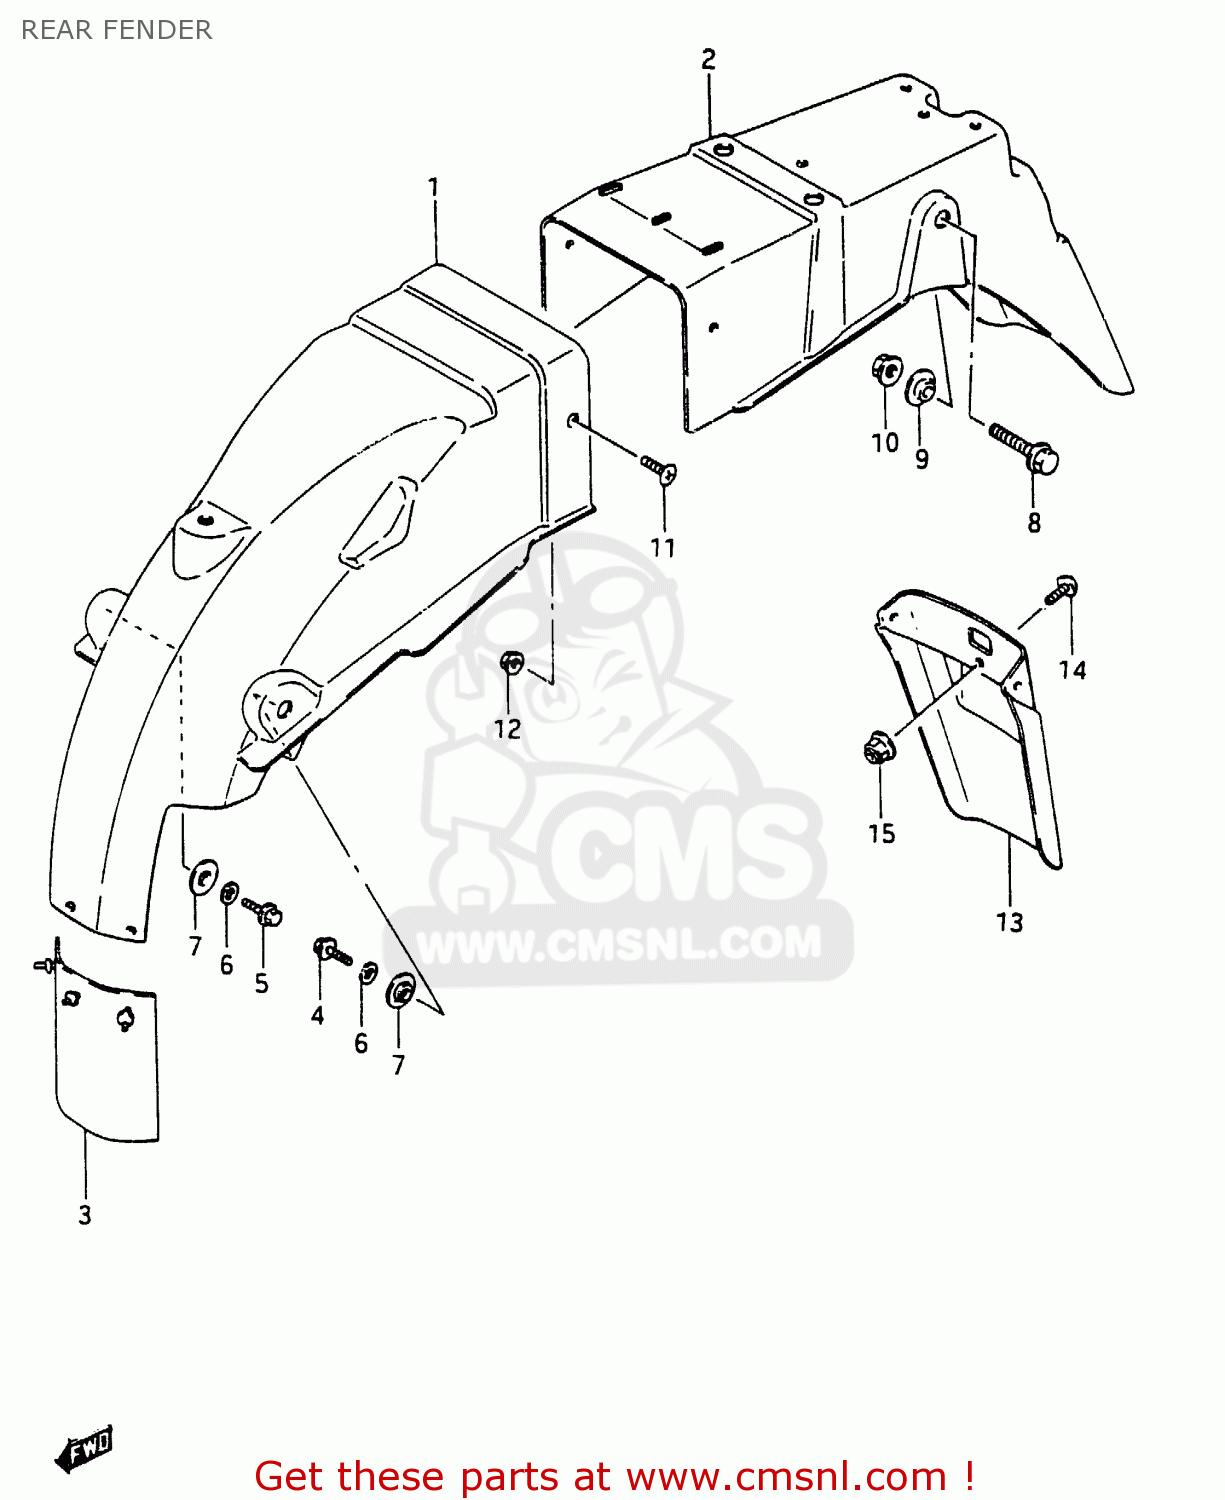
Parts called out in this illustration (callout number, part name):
1	BODY, REAR FENDER FRONT
2	BODY, REAR FENDER REAR
3	MUD GUARD
4	BOLT
5	BOLT
6	WASHER
7	WASHER
8	BOLT
9	WASHER
10	NUT
11	SCREW
12	NUT
13	EXTENSION, REAR FENDER
14	SCREW
15	NUT
